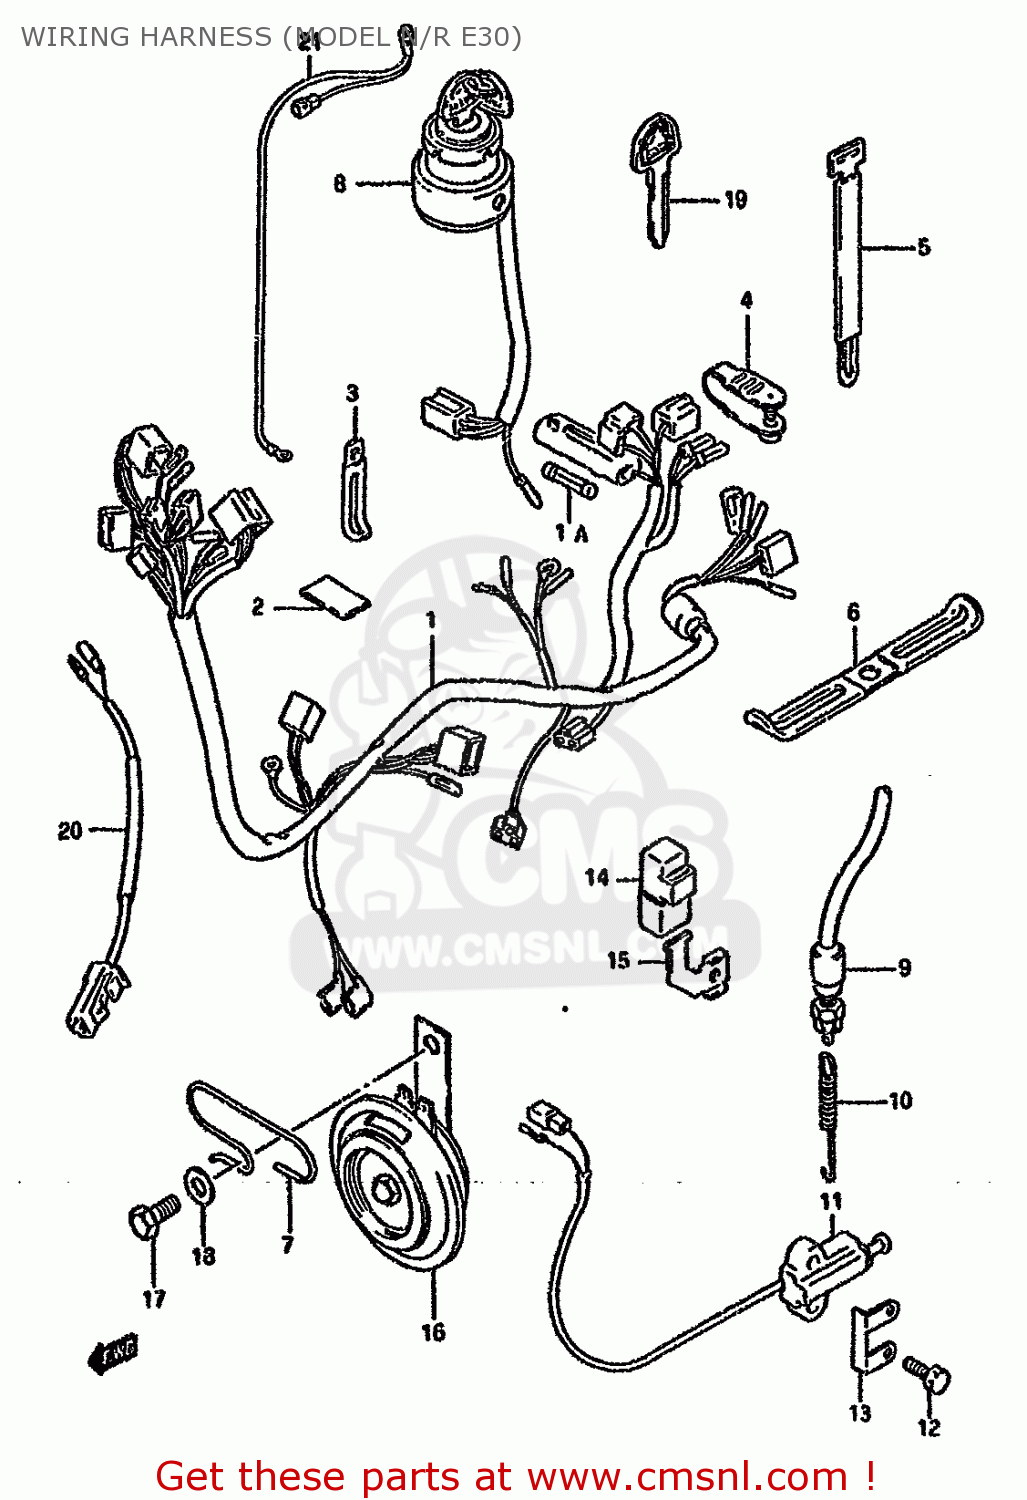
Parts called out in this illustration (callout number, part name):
1	HARNESS,WIRING
1A	FUSE(15A)
2	TAPE
3	CLAMP
4	CLAMP,L:88
5	CLAMP(L:125)
6	CLAMP,STARTER MOTOR LEAD
7	CLAMP,WIRING HARNESS
8	SWITCH ASSY,IGNITION
9	SWITCH ASSY,STOP LAMP
10	SPRING
11	SWITCH ASSEMBLY,SIDE STAND
12	BOLT
13	KEY,BLANK
14	RELAY ASSEMBLY
15	RELAY ASSEMBLY
16	HORN ASSEMBLY
17	BOLT
18	WASHER
19	BOLT
20	WIRE,CLUTCH SWITCH LEAD
21	WIRE,BATTERY PLUS LEAD
